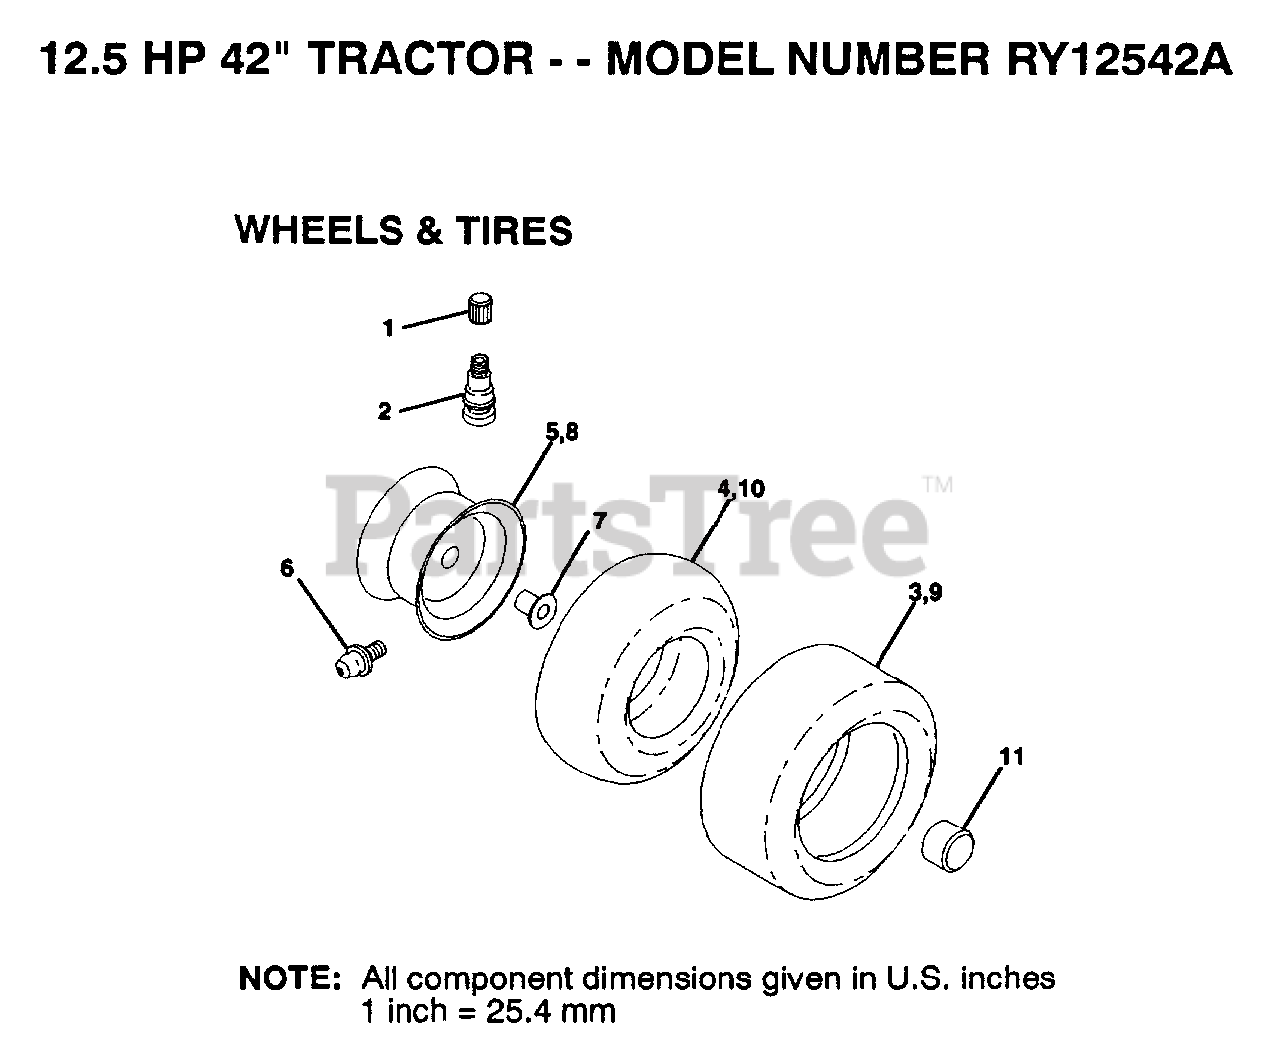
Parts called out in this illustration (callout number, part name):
1	VALVE CAP
2	VALVE STEM LT
4	TUBE.5.3/4.5/6
6	FITTING LT
7	"FLANGE, BEARING"
10	TUBE.18X9.5-8
11	HUB CAP
